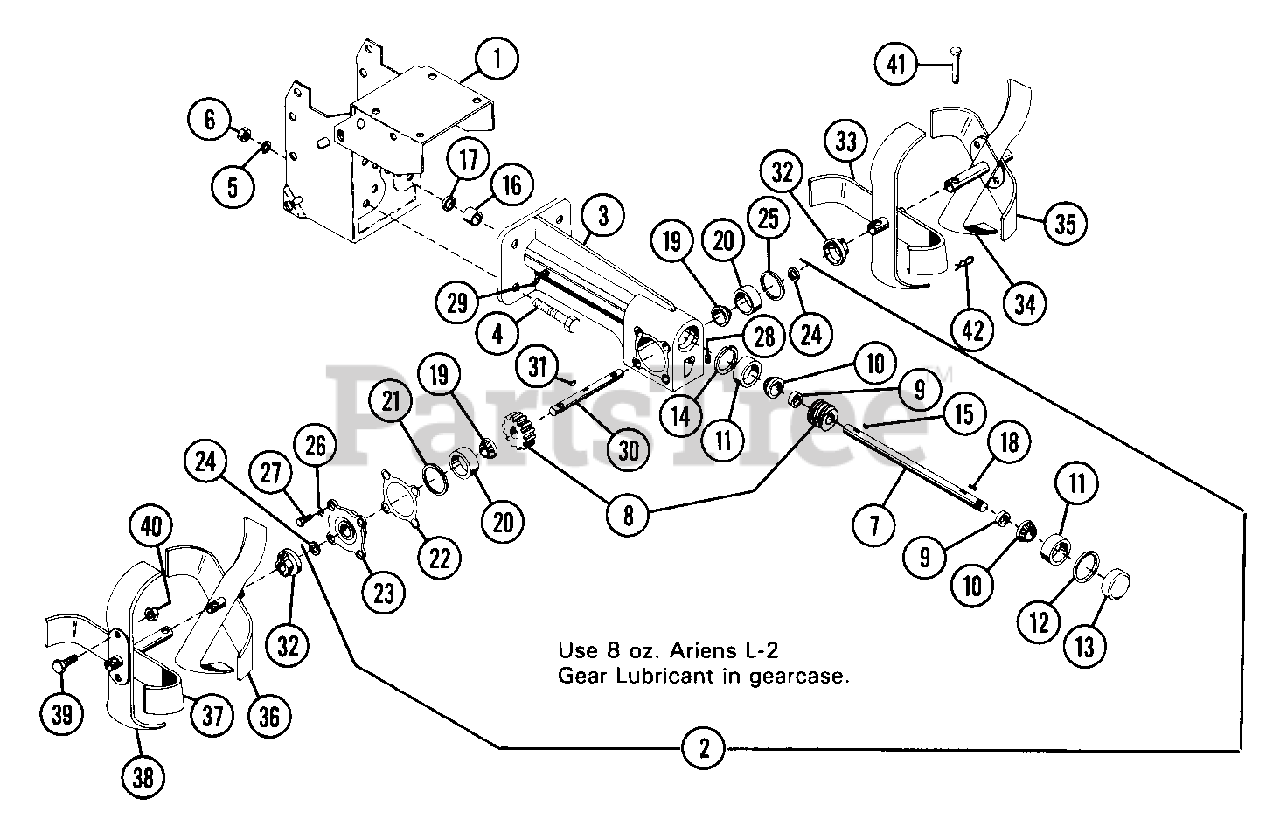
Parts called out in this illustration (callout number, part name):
1	FRAME
2	GEAR CASE - CAST IRON
3	WORM GEAR HOUSING
4	BLT-HEX .38-16X1.25 PL GR 2
5	WSHR-LK .375X.115 HVY PL
6	NUT-HEX .375-16
7	WORM SHAFT
8	WORM GEAR AND WORM - KIT
9	BSHG, SPCR .755X1.12X.50 PM
10	BRG-CONE .750X.61
11	BRG-CUP 1.781X.475
12	SNAP RING KIT
13	DUST CAP
14	RG-RTNG-INT 1.781X.062
15	KEY-WDRF .188X.875X.375 SAE11
16	BRG-NEEDLE .750X1.0X.62
17	SEAL .750X1.000X.125
18	KEY-SQ .188X1.0X.188 SAE 8630
19	BRG-CONE 1.0X.58
20	BRG-CUP1.980X.420
21	SNAP RING KIT
23	BEARING FLANGE
24	SEAL 1.000X1.980X.375
25	RG-RTNG-INT 1.969X.062
26	WSHR-LK .312X.097 PL HVY
27	BLT-HEX .31-18X.88 PL GR2
28	PIPE PLUG
29	BREATHER
30	TINE SHAFT
31	KEY-WDRF .25X.875X.375 SAE A
32	DUST CAP
33	L H INNER TINE SPOOL
34	L H OUTER TINE SPOOL
35	L H TURBO-TINE
36	R H INNER TINE SPOOL
37	R H OUTER TINE SPOOL
38	R H TURBO-TINE
39	BLT-HEX .44-14X1.00 GR5
40	NUT-LK-TOP .437-14 GR C PL
41	CLEVIS PIN
42	PIN-HAIR INT .08X.38X1.42 YWZC
